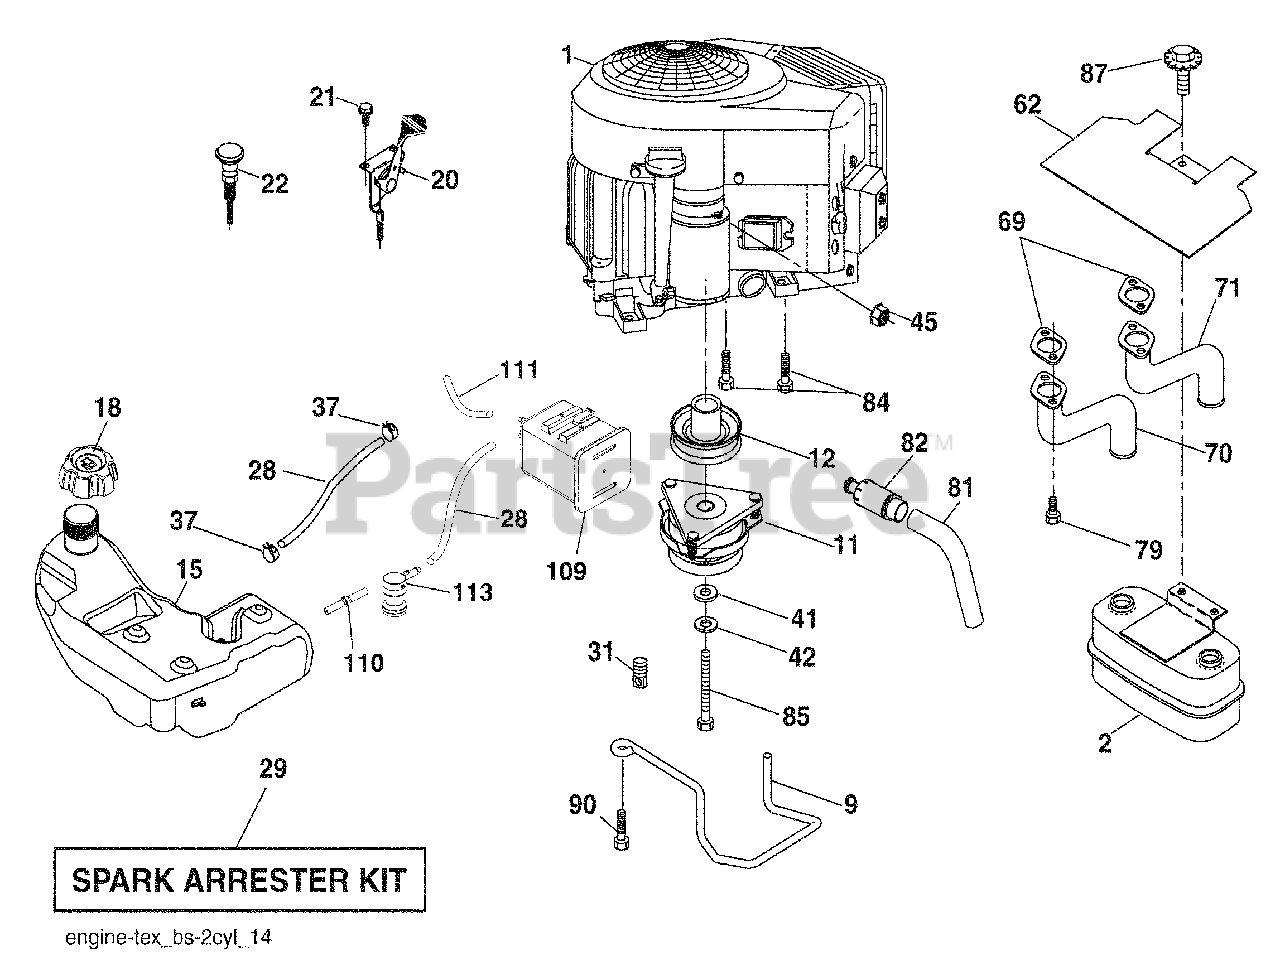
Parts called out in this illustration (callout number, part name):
9	Keeper Belt Engine
11	Clutch Electric
12	Pulley Engine
18	Cap Asm
20	Control Throttle
21	Screw #10 x 0.750 BOS Thread
22	Control Choke
28	Fuel Line
29	Spark Arrester Kit
31	Clip Push-In
37	Clamp Hose
41	Washer 1-1/2 OD x 15/32 ID x .250
42	Washer Lock 7/16
45	Nut Keps Hex 1/4-20 unc
62	Shield Heat Muffler
70	Tube Exhaust LH
71	Tube Exhaust RH
79	Screw Socket Head 5/16-18 x 1
81	Tube Drain Oil Easy
82	Plug Drain Oil
84	Screw 3/8-16 x 1-1/4
85	Bolt Hex 7/16-20 x 4 Gr. 5
87	Bolt 5/16-18 unc x 1 w/Sems
90	Screw 3/8-16 x 1
109	Canister Carbon Filter Asm.
110	Valve Anti-slosh
111	Purge Line
113	Valve Slant Cartrdg
